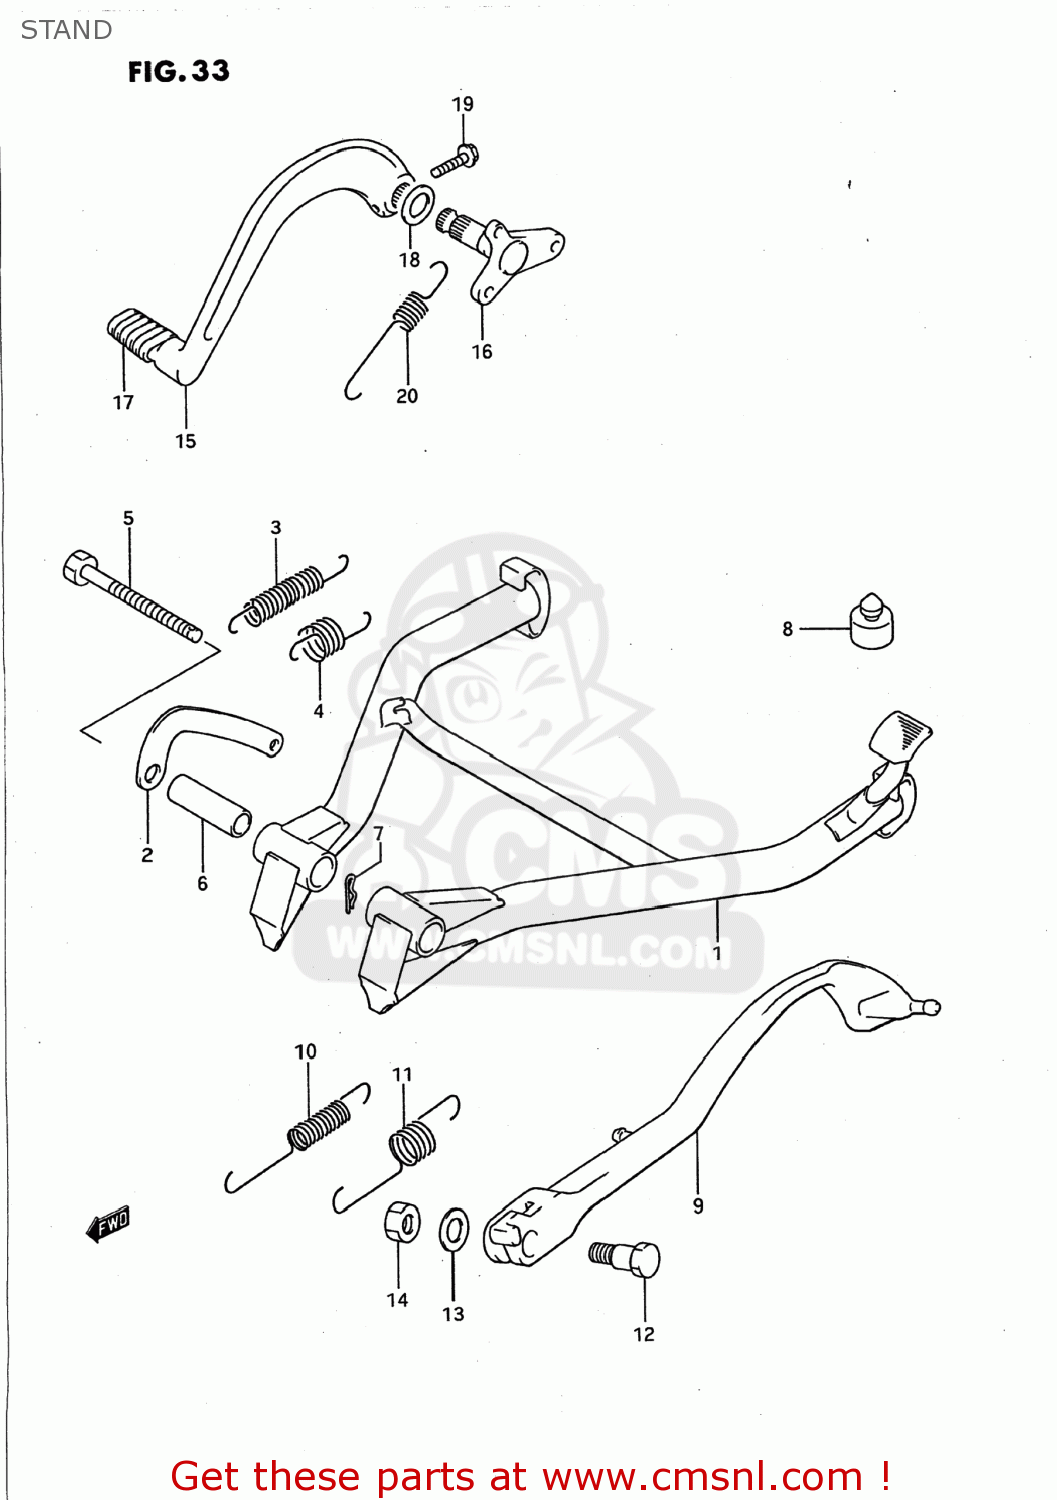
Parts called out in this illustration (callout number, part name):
1	STAND,CENTER
2	HOOK,CTR STAND SPRING
3	SPRING
4	SPRING
5	BOLT
6	SPACER(10X16X38.8)
7	CLIP
8	CUSHION
9	STAND,PROP
10	SPRING
11	SPRING
12	BOLT(10X38)
13	SHIM
14	NUT
15	PEDAL,BRAKE
16	BOSS,BRAKE ROD
17	RUBBER,BRAKE PEDAL
18	WASHER,BRAKE PEDAL
19	BOLT
20	SPRING
